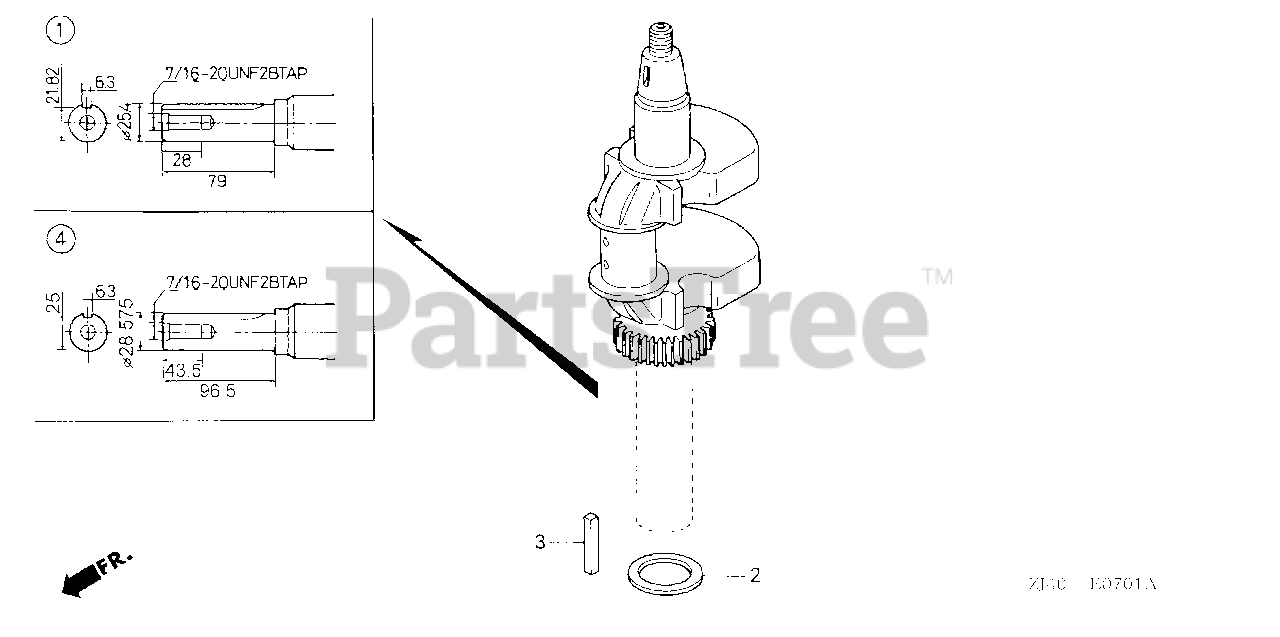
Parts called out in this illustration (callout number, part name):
1	CRANKSHAFT
2	WASHER, CRANKSHAFT THRUST (38.5X54.0X1.0)
3	KEY (6.3X6.3X43)
